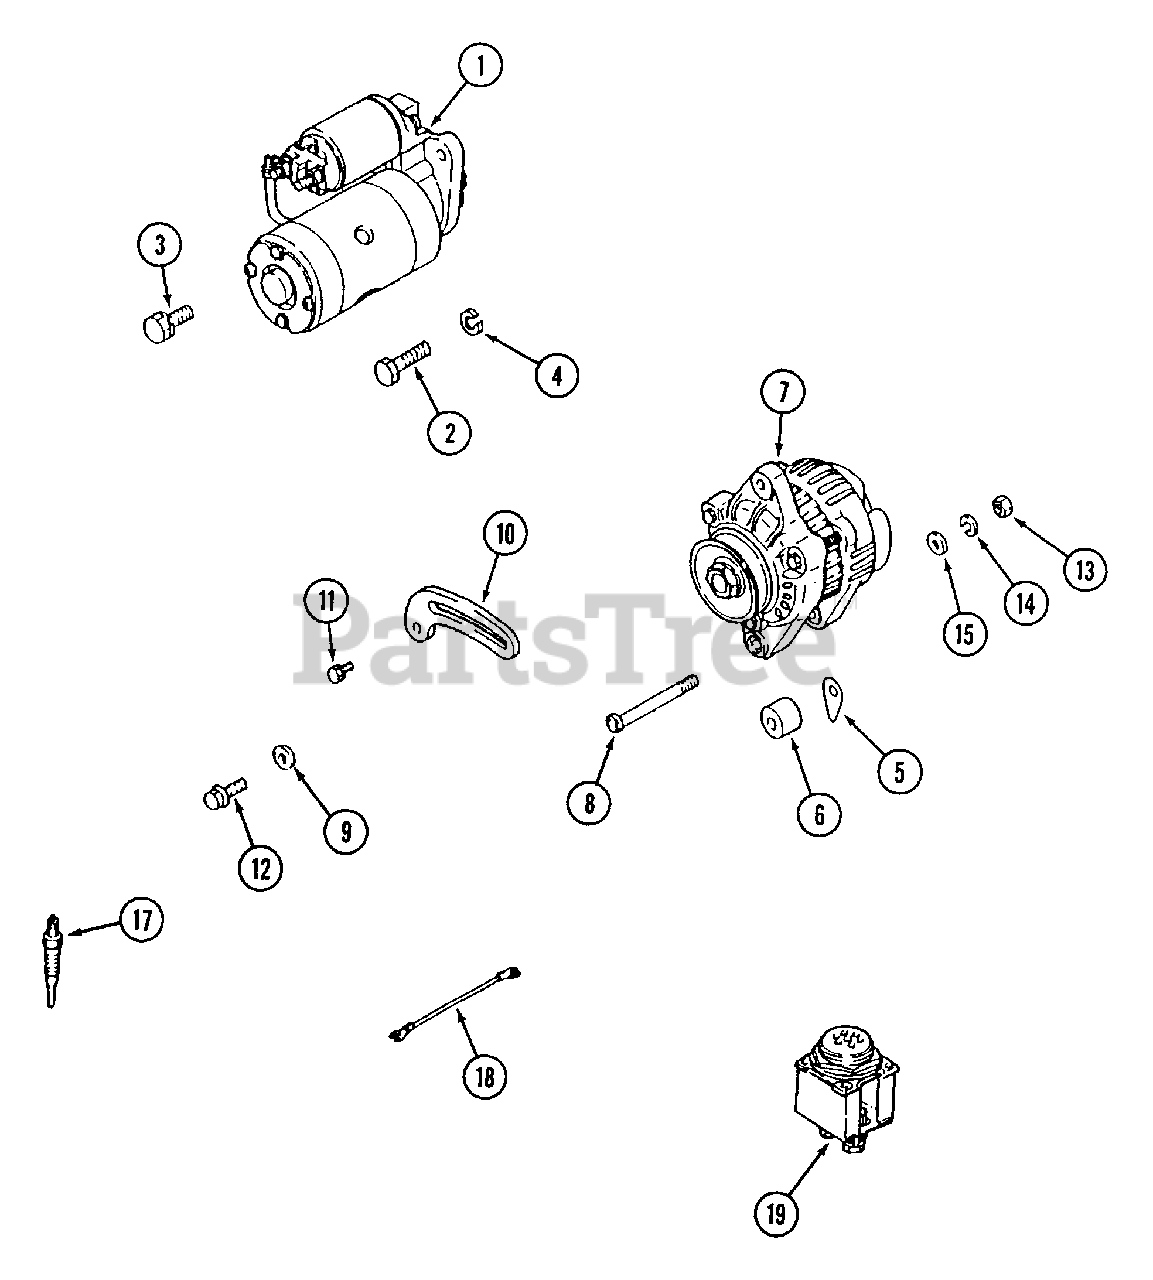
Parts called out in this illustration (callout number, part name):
1	Starter Ass'y.
2	Bolt, Starter
3	Bolt,
4	Washer, Lock
10	Brace, Generator
11	Bolt,
12	Bolt, Flange
14	Washer, Lock
15	Washer, Flat
17	Plug, Glow
18	Wire, Glow Plug Lead
19	Lamp, Glow
